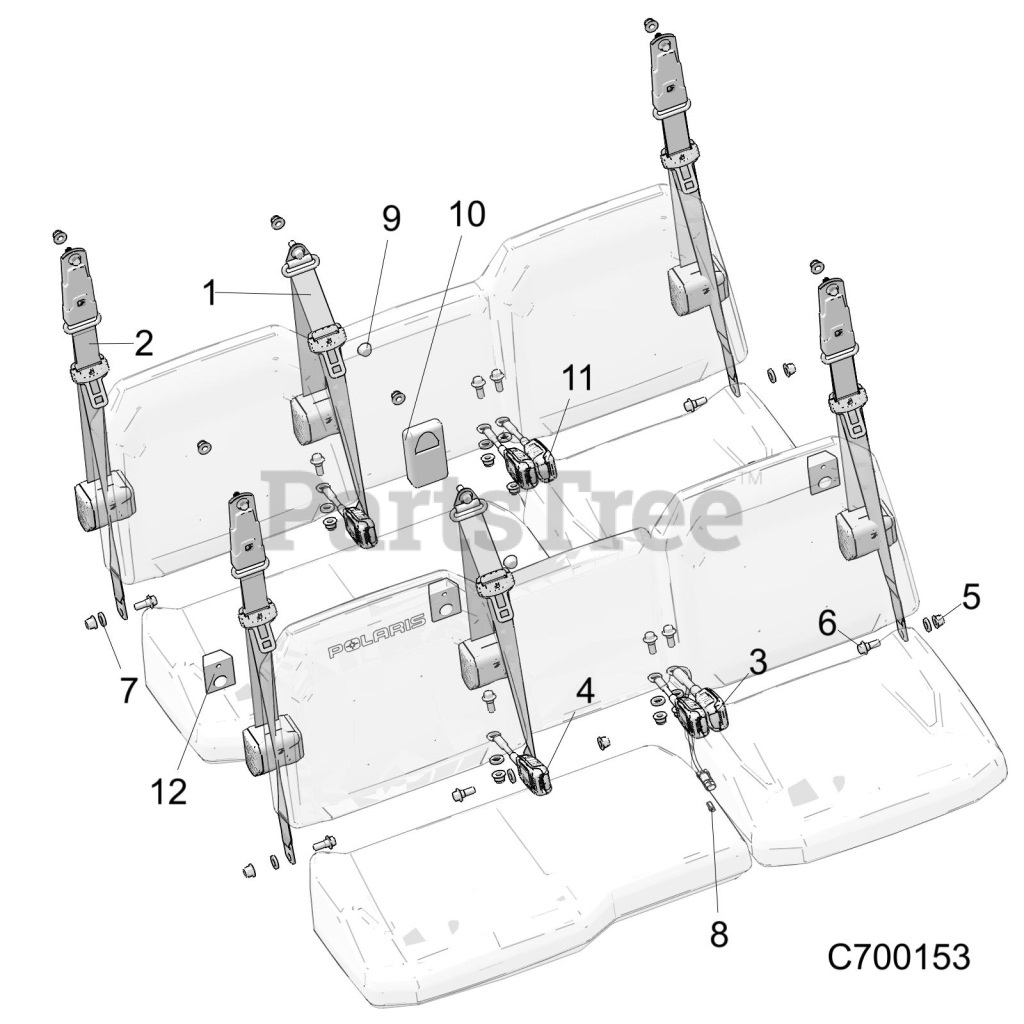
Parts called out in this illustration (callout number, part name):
1	ASM-SEAT BELT,3PT,CENTER
2	ASM-SEAT BELT,3PT
3	BUCKLE, SEATBELT, 90, SWITCH
4	BUCKLE-SEATBELT,9.6,PASSENGER
5	NUT-HXFL M12X1.75 NYLOC ZOD
6	SCR-HXFLSH-M12X1.75-M14X9 ZOD
7	WASHER-SEATBELT,RUBBER
8	CLIP-CONNECTOR,6.35MM HOLE
9	CAP-BOLT HEAD
10	COVER-SEAT BELT MOUNT
11	BUCKLE-SEATBELT,9.6,DRIVER
12	PAD-REAR,SEAT BASE
